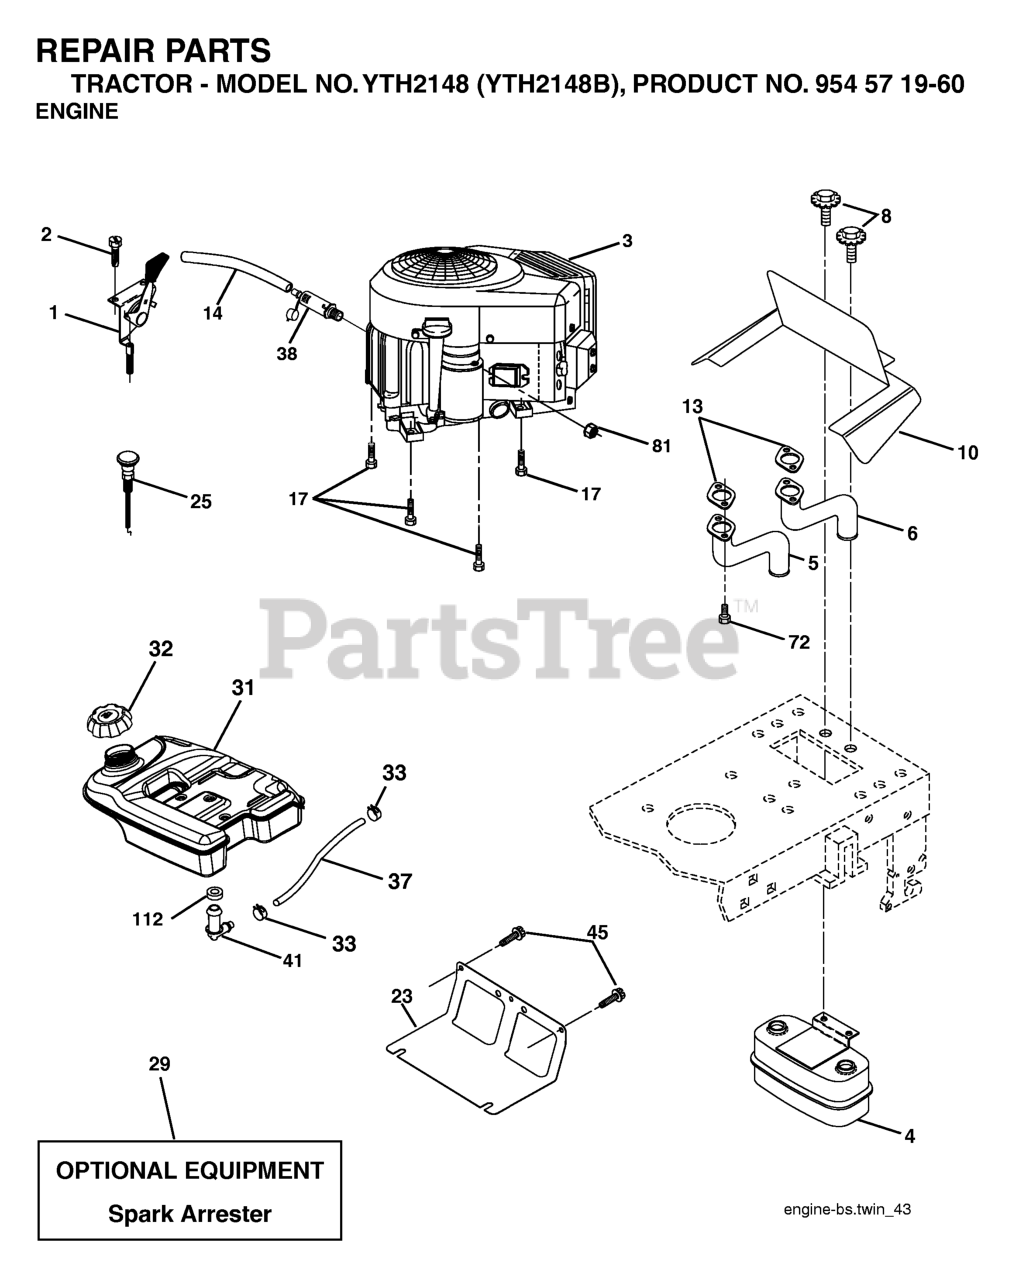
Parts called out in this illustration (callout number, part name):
1	THROTTLE CONTROL
2	SCREW
4	MUFFLER.TWIN.CYL.LOW.TONE
5	RP.EXHAUST.TUBE.LH.BS/TWIN
6	EXHAUST.TUBE.RH.BS/TWIN
8	BOLT.5/16-18UNCX3/4 W/SEMS.BLK
10	SHIELD.BROWNING.B&S
13	GASKET.MUFFLER
14	TUBE, DRAIN OIL ASM.
17	SCREW 3/8-16 X 1-1/2
23	SHIELD.BROWNING.DBR.GUARD
25	CONTROL THROTTLE
26	Nut Keps 3/8 - 24 UNF
29	KIT.SPARK ARRESTOR 794945 B&S
31	4.0 REAR FUEL TANK
32	TANK CAP
33	HOSE CLAMP
37	REPL BY 532 00 85-43
38	PLUG DRAIN OIL EASY
41	STEM FUEL TANK
45	SCREW, 3/8-16X3/4
72	SCREW.SOCKET.HEAD.5/16-18
81	NUT
112	BUSHING OUTLET T
